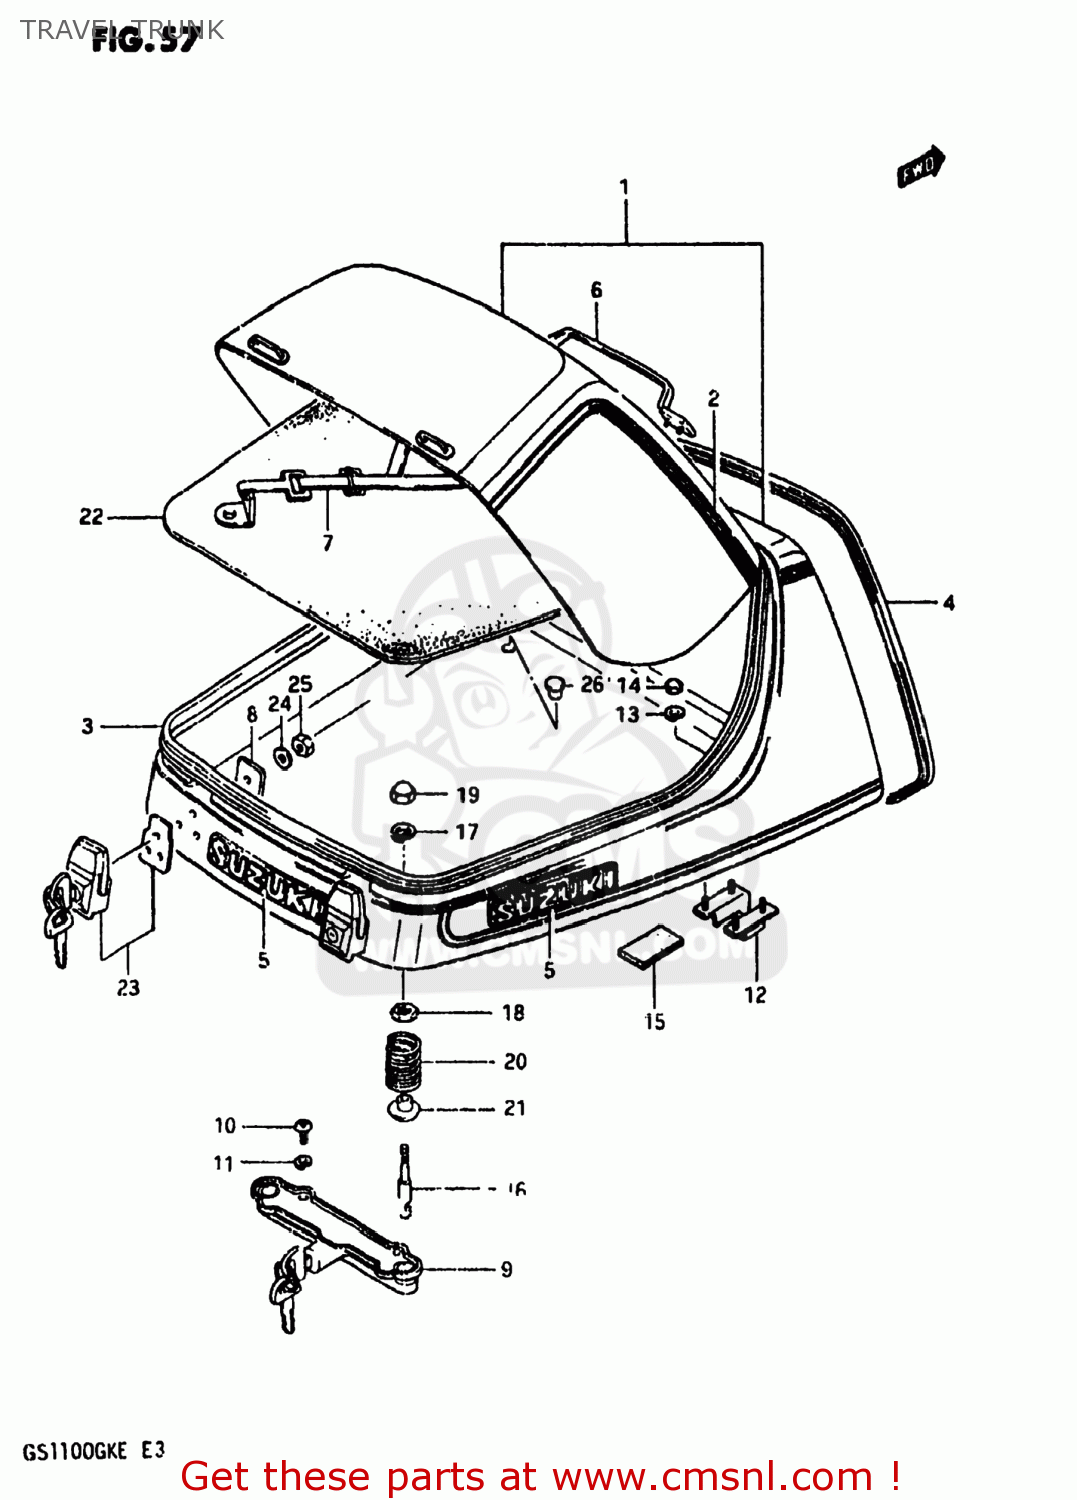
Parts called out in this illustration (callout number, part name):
2	TAPE SET,COWLING BODY
3	SEAL,TRAVEL TRUNK
4	MOLDING,TRAVEL TRUNK
5	EMBLEM
6	GRIP TRAVEL TRUNK
7	BAND SET
9	LOCK,TRAVEL TRANK
10	SCREW 6X12
11	LOCK WASHER
12	HOOK COMP TRAV TRUNK
13	WASHER,LOCK
14	NUT
15	CUSHION TRAVEL TRUNK
16	LOCK BOSS TRAV TRUNK
17	LOCK WASHER
18	NUT 8MM
19	NUT,M8X1.25X12
20	SPRING,TRAVEL TRUNK
21	GUIDE,TRAVEL TRUNK SPRING
22	CUSHION TRAVEL TRUNK
23	LOCK,TRANK LID
24	WASHER
25	NUT
26	PLUG(OD:14)
